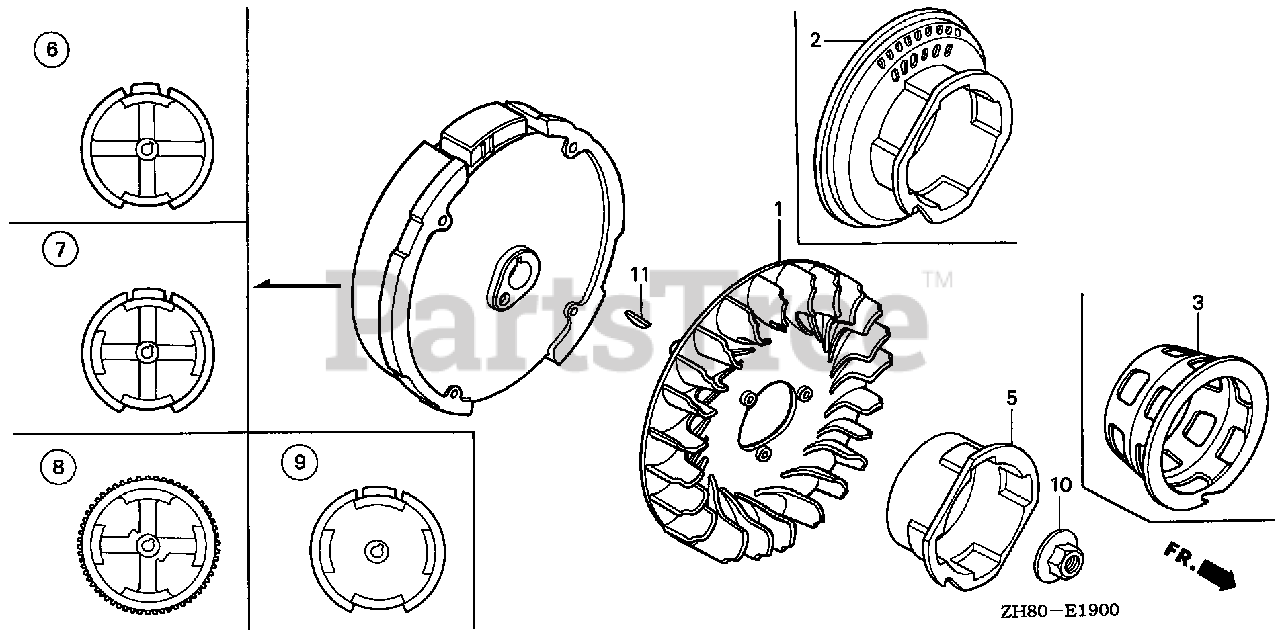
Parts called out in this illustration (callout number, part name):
1	FAN, COOLING
5	PULLEY, STARTER
7	FLYWHEEL (LAMP)
10	NUT, SPECIAL (14MM)
11	KEY, SPECIAL WOODRUFF (25X18)
